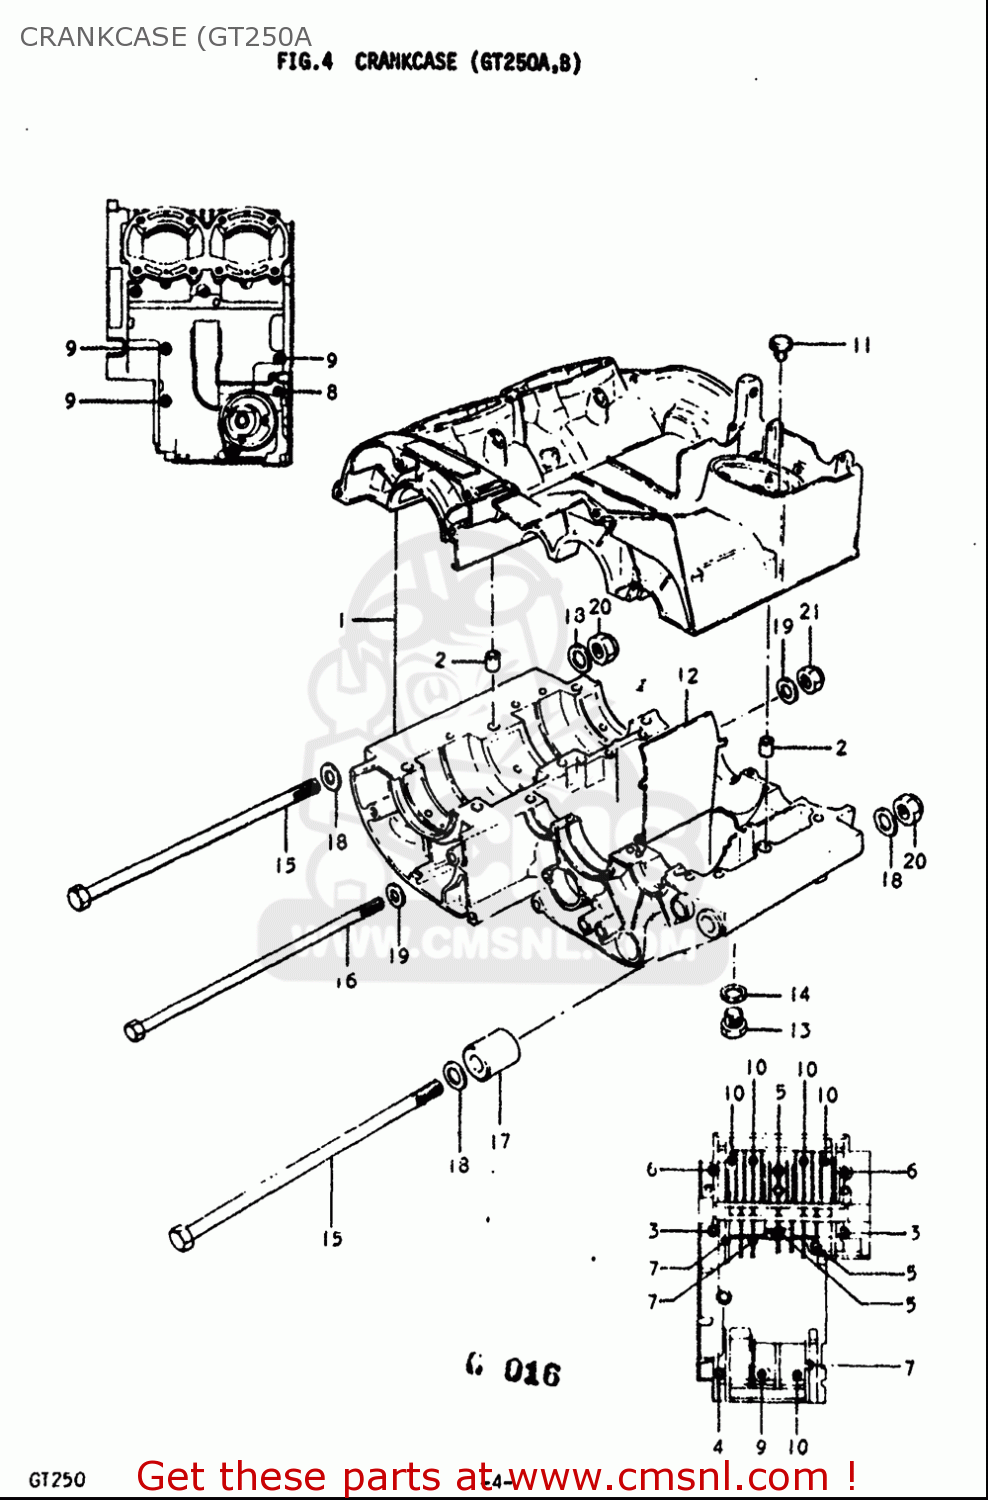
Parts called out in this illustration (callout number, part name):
2	PIN
3	BOLT
4	BOLT
5	BOLT
6	BOLT
7	BOLT
8	BOLT
9	BOLT
10	BOLT
13	PLUG
14	GASKET(14X19.2X2) (NAS)
17	SPACER
18	WASHER
19	WASHER
20	NUT
21	NUT
